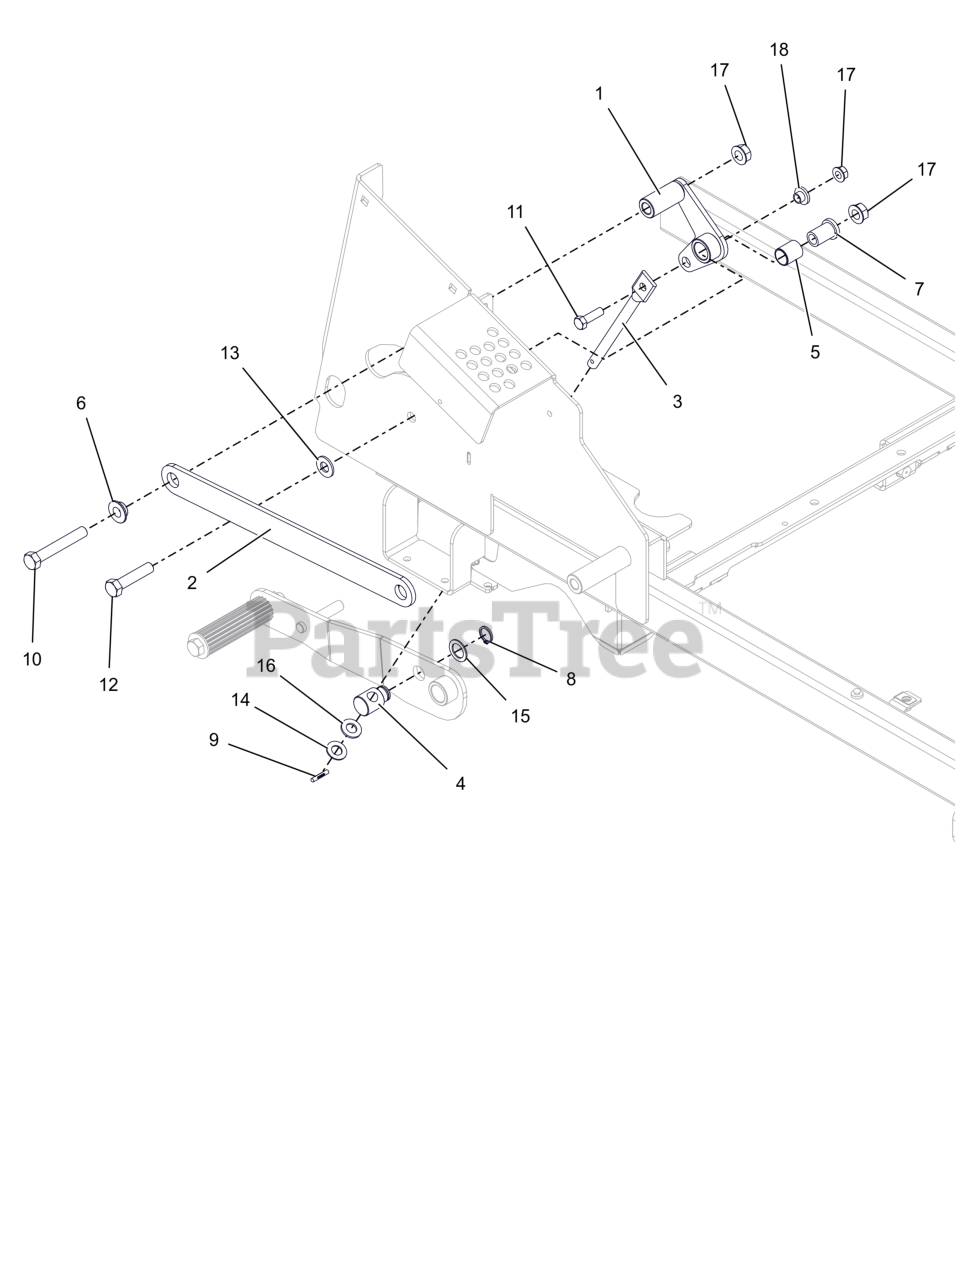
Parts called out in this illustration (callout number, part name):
1	WLDMT, PIVOT BRKT
2	LINK,DECK LIFT FOOT ASSIST
3	LINK, HOC FOOT
4	TRUNNION,DECK LIFT FOOT ASSIST
5	BRG, .750 X .875 X 1.000
6	BSHG, FLG .515X.750X.360X1.12
7	BSHG-FLG .515X.746X1.290X1.000
8	RG-RTNG-EXT .689X.078
9	PIN-GRV .188X1.00 TP E
10	BLT,HEX .50-13X3.25 G5 ZCC
11	BLT, HEX .38-16X1.25 G5 ZCC
12	BLT, HEX .50-13X2.25 G5 ZCC
13	WSHR,FLT .531X1.062X.095 ZCC
14	WSHR, FLT .531X1.00X.063 ZCC
15	WSHR, FLT .754X1.125X.062 ZCC
16	WSHR, RUBBER .332X1.000X.094
17	NUT, FLG-CTR LK .
18	BSHG-FLG .385X.500X.875X.406
